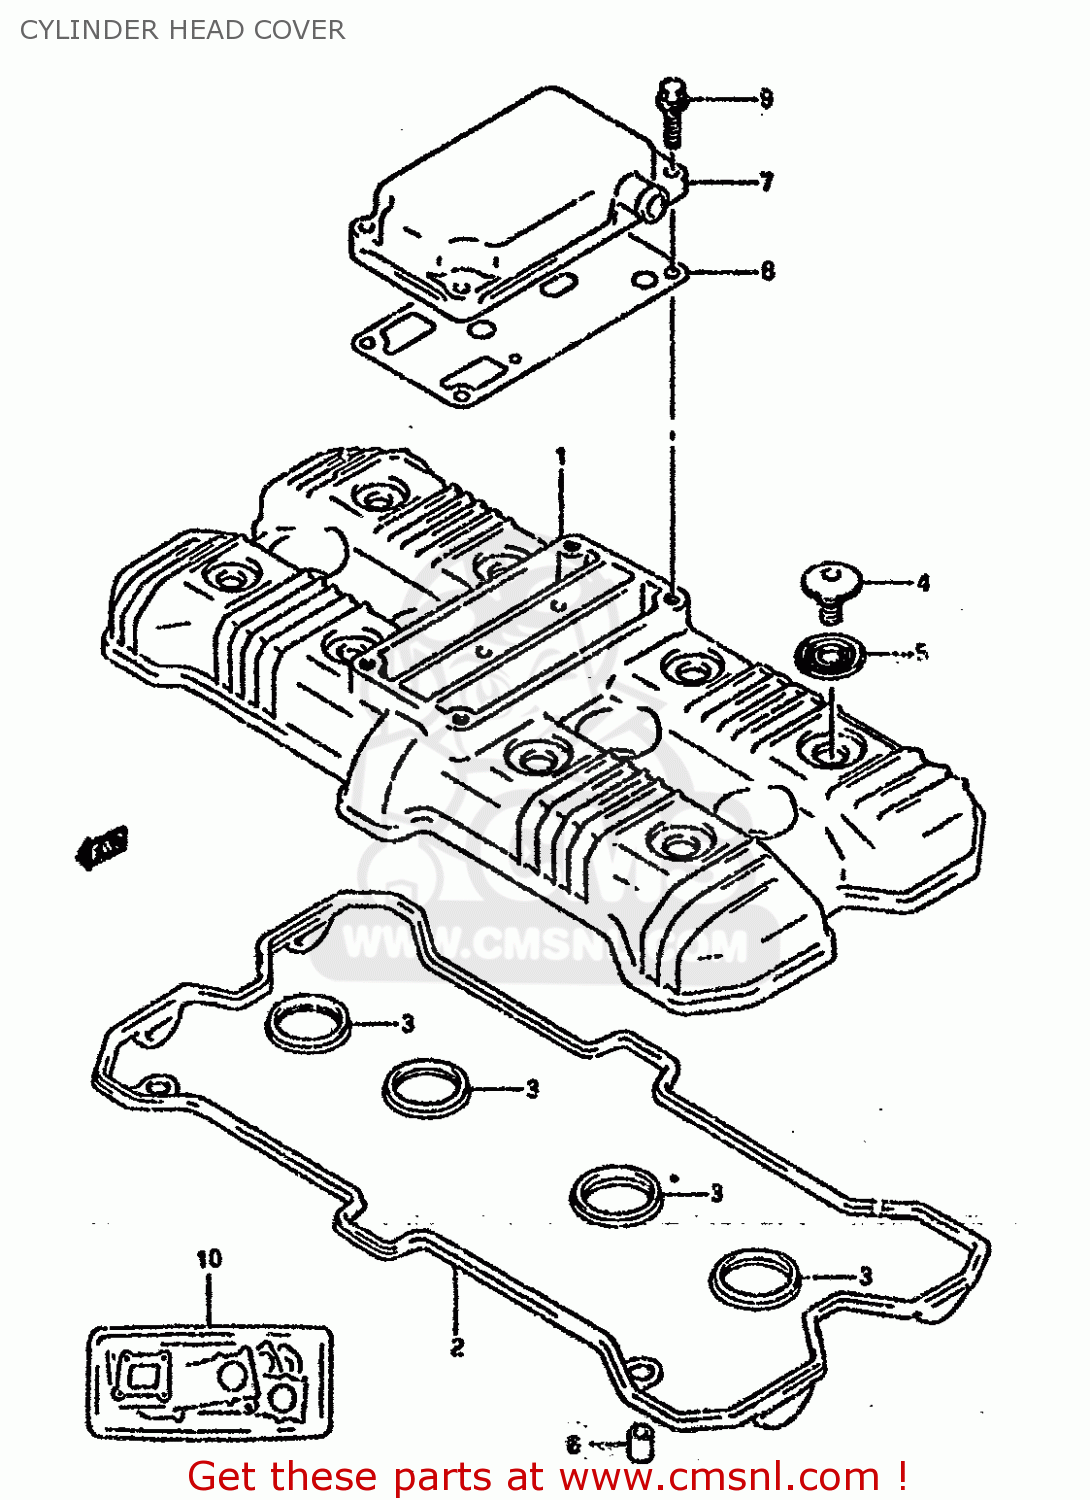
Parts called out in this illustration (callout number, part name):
1	COVER,CYLINDER (MG)
2	GASKET,CYL HEAD COVER NO.1
3	GASKET,CYL HEAD COVER NO.2
4	BOLT(7X17.5)
5	WASHER(10.6X25.5X2.3)
6	PIN(6.2X8X11)
7	COVER,BREATHER
8	GASKET,BREATHER COVER
9	BOLT
10	GASKET SET (NAS)
